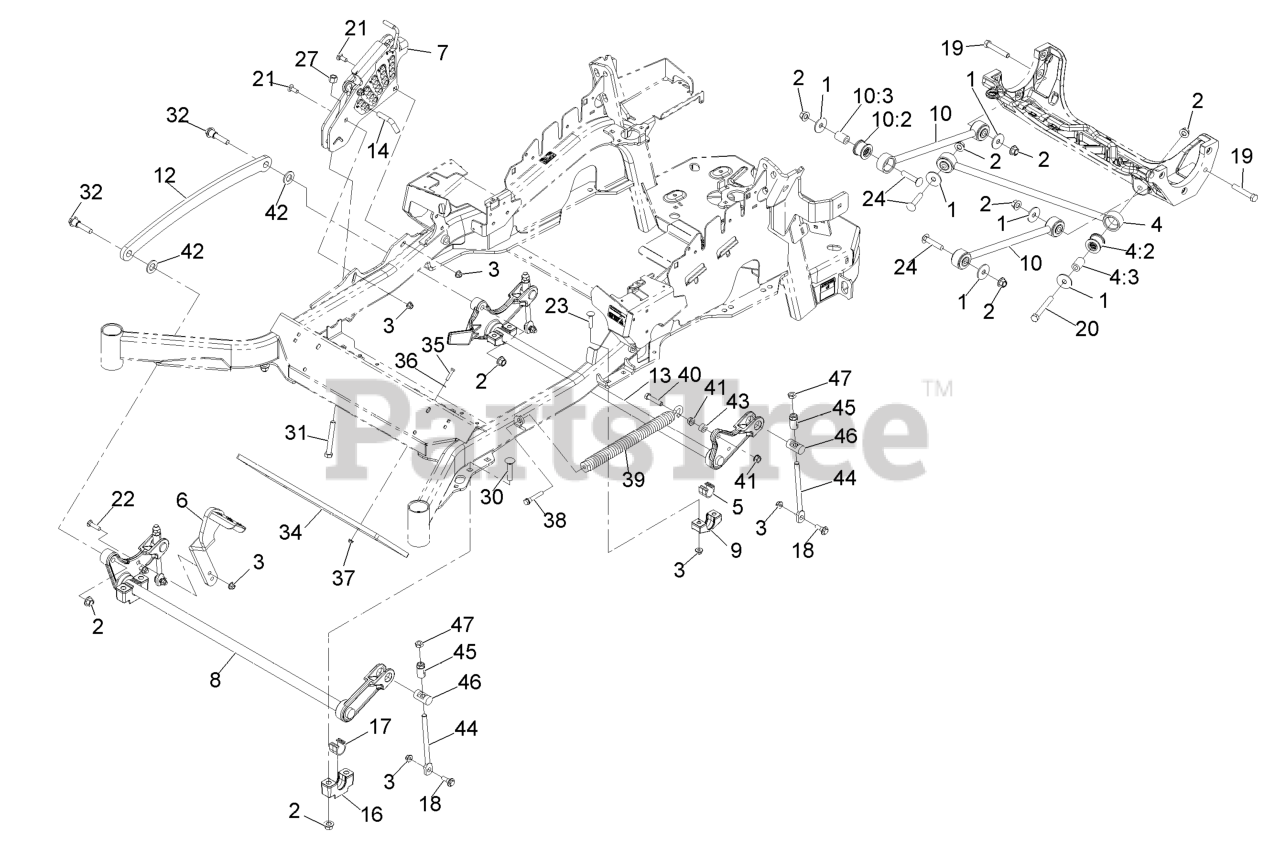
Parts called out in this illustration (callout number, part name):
1	WASHER-THRUST
2	Nut-Lock 1/2-13
3	NUT-HF, NI
4	PANHARD ROD ASM
4:2	BUSHING-SUSPENSION, RUBBER
5	BEARING-CROSS SHAFT, REAR
6	LEVER-FOOT
7	HOC ASM
10	DECK STRUT ASM
10:2	BUSHING-SUSPENSION, RUBBER
12	LINK-LIFT, DECK
13	LIFT-DECK, REAR
14	PIN-HOC
16	SUPPORT-CROSS SHAFT, BEARING
17	BEARING-CROSS SHAFT, FRON
18	SCREW-SHOULDER, HHF
19	SCREW-HH
20	SCREW-HH
21	BOLT-CARR
22	SCREW-CARR
23	SCREW-CARR
24	SCREW-CARR
27	NUT-LOCK, NI
30	Bolt-Carriage 1/2-13 X 2 1/2 Spl Neck
31	BOLT-TAP
32	SCREW-HHF, SHOULDER
34	WEIGHT,TOE BOARD
35	SCREW-HH
36	WASHER-FLAT
38	BOLT-SHOULDER
39	SPRING-EXTENSION
40	SCREW-HH
42	WASHER-FLAT
44	LINK-ADJUSTER, DECK LIFT
45	ADJUSTER-LIFT, DECK
46	TRUNNION
47	NUT-JAM
